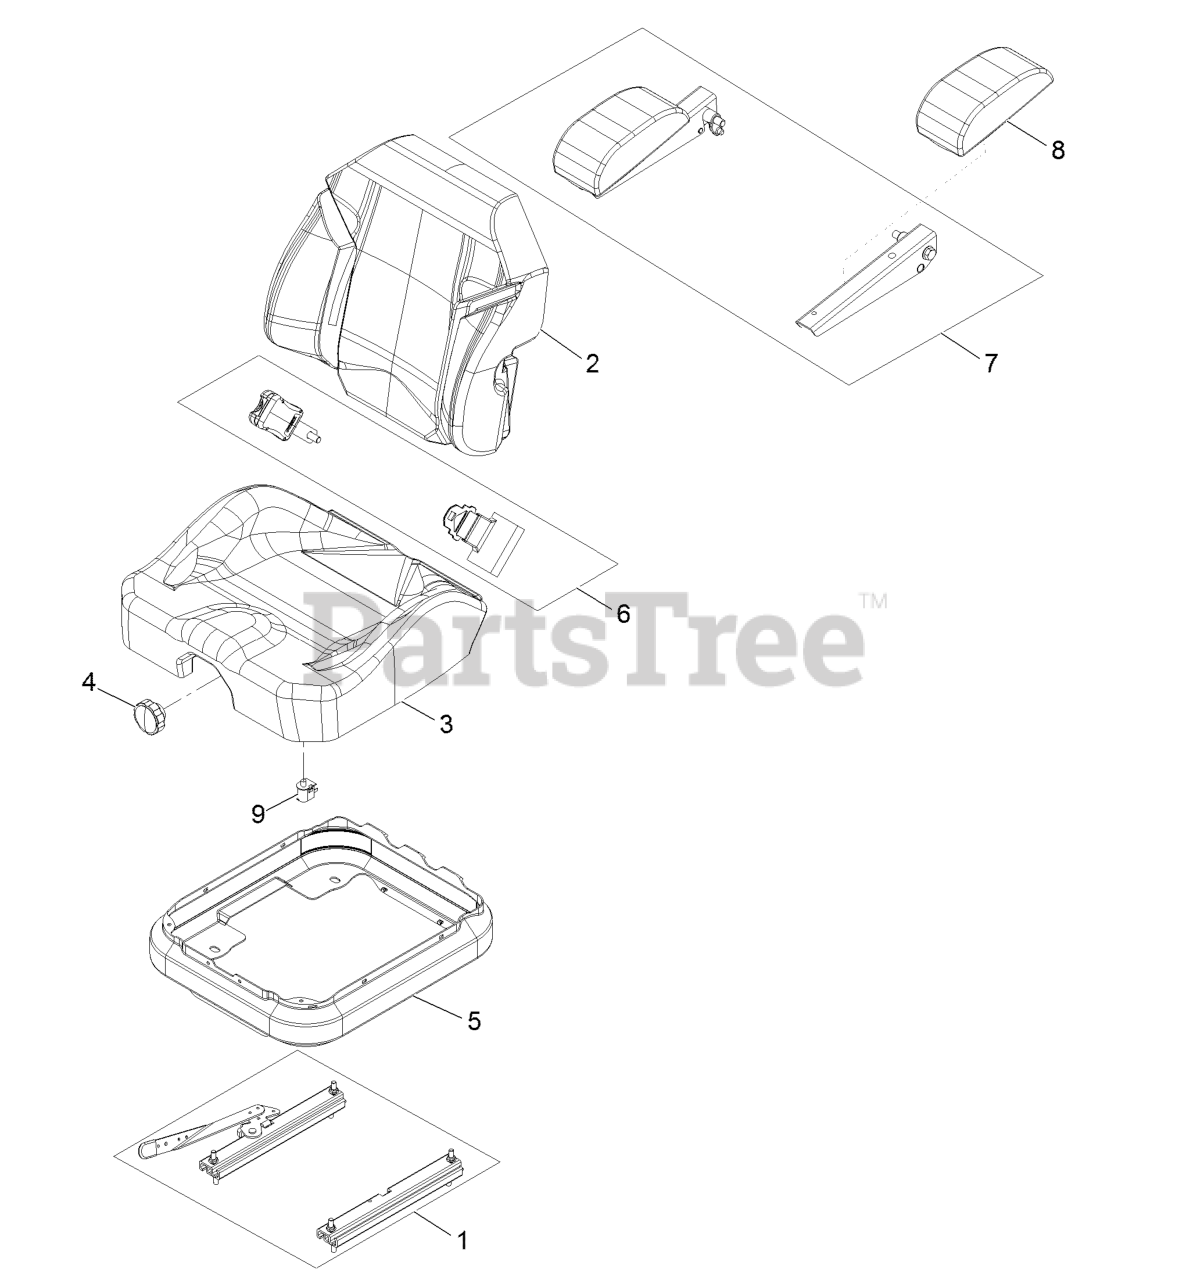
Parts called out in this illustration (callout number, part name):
1	SEAT TRACK SET
2	COVER-BACK 310951VN476
3	COVER-CUSHION 310952VN476
4	KNOB-ADJUSTER
5	COVER-SUSPENSION, BELLOWS
6	SEAT BELT KIT
7	ARM REST SET
8	ARM REST PAD SET
9	SWITCH-BAIL
